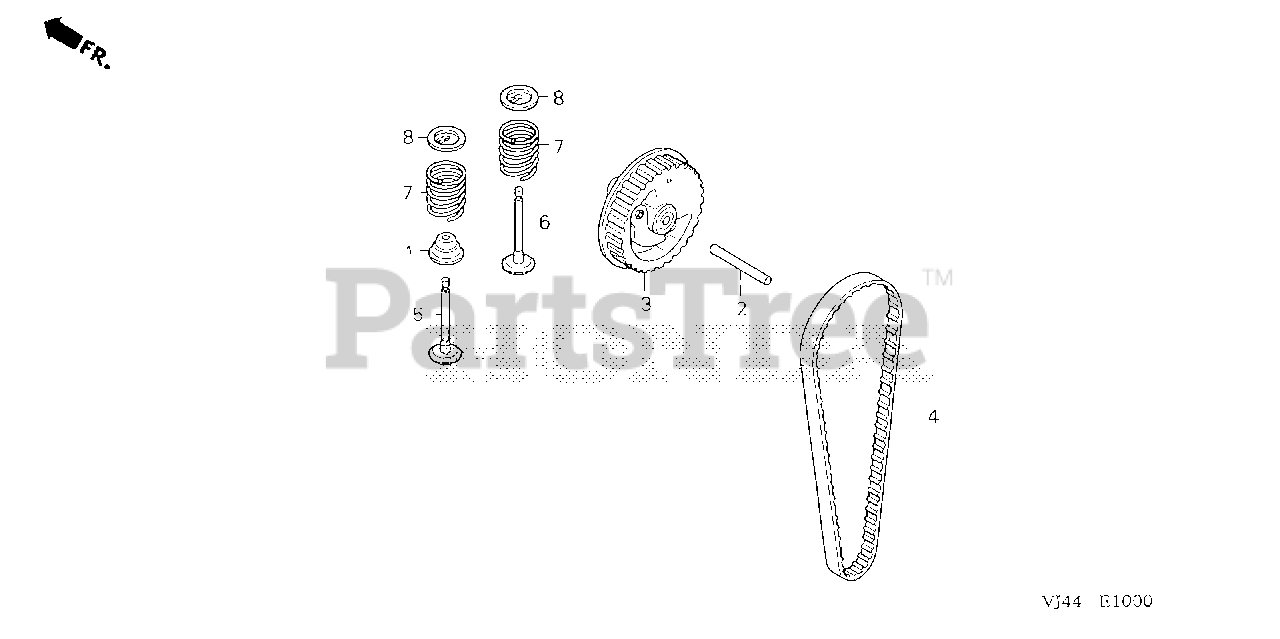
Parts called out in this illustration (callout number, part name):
1	SEAL, VALVE STEM
2	ROLLER (4X29.8)
3	PULLEY, CAMSHAFT
4	BELT, TIMING (71ZU6 G-300)
4	BELT, TIMING (71ZU5 G-310)
5	VALVE, IN. (EI)
6	VALVE, EX. (EE)
7	SPRING, VALVE
8	RETAINER, VALVE SPRING
